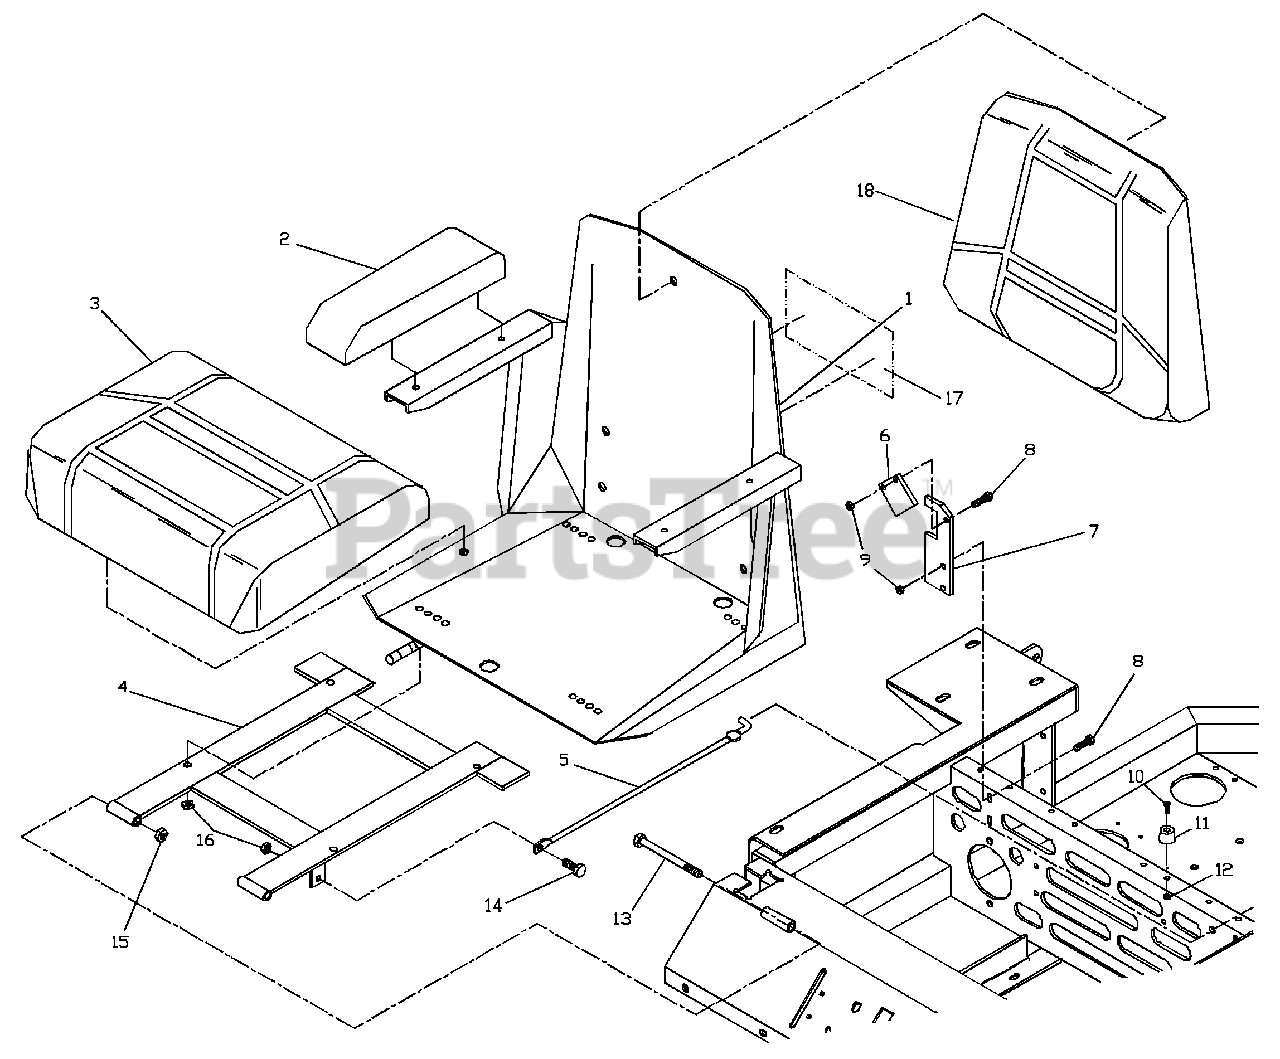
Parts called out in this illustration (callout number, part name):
1	SEAT, COMPLETE
2	ARM REST CUSHION
3	SEAT CUSHION W / SWITCH
4	SEAT MOUNT FRAME
5	SEAT STOP ROD
6	SEAT LATCH
7	SEAT LATCH MOUNT
8	1/4C X 3/4 HEX CAP SCREW
9	1/4C CENTERLOCK NUT
10	#10-24 X 7/8 SLOTTED SCREW
11	SEAT BUMPER
12	#10-24 NYLOC NUT
13	3/8C X 5 HEX CAP SCREW
14	5/16C X 1 HEX CAP SCREW
15	3/8C CENTERLOCK NUT
16	5/16C CENTERLOCK NUT
17	DECAL, CROWN
18	SEAT BACK CUSHION
